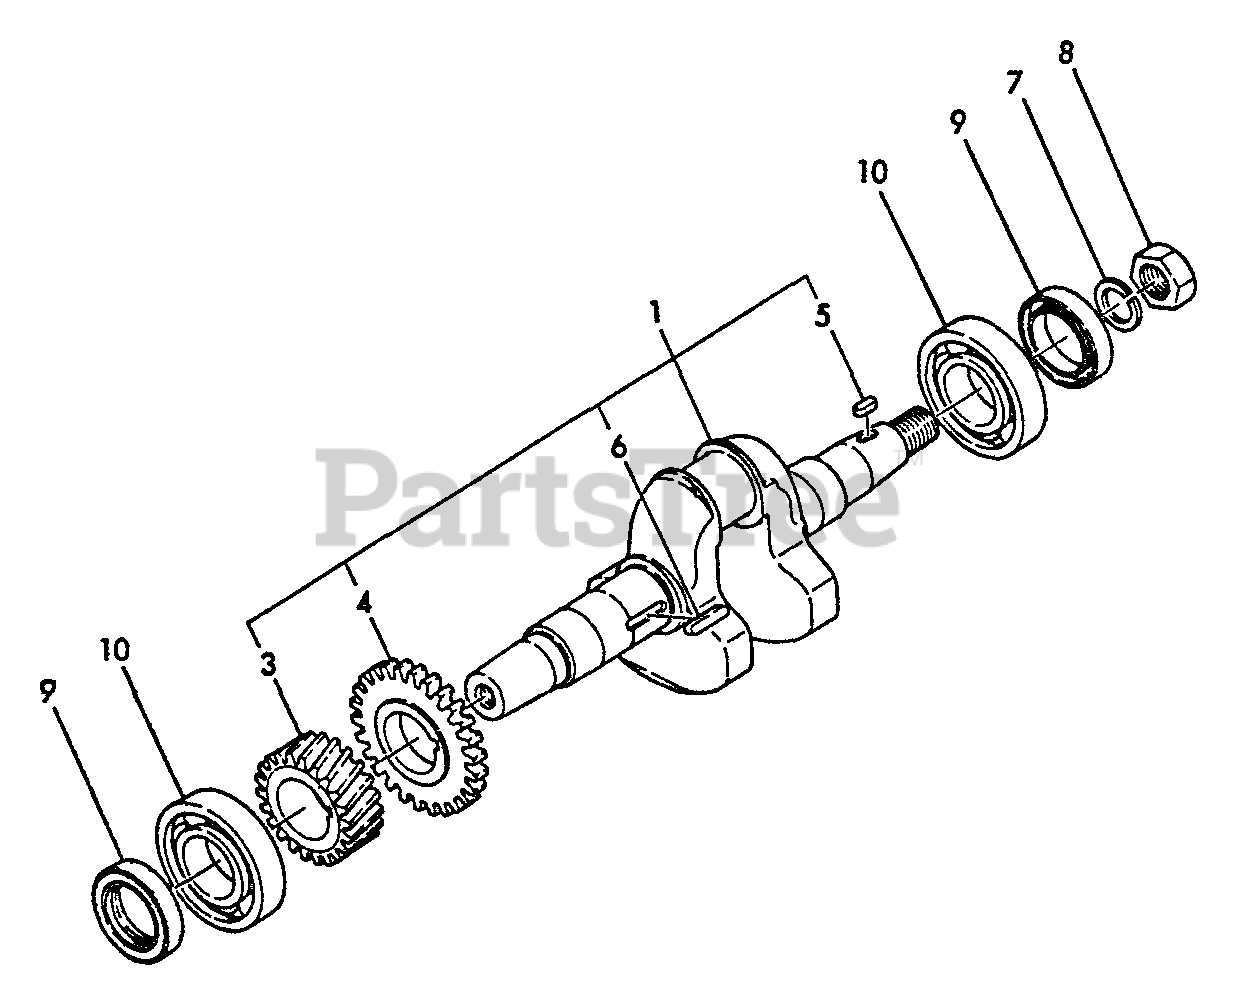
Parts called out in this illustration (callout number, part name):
1	CRANKSHAFT ASSY
3	GEAR, CRANKSHAFT
4	GEAR, BALANCER
5	KEY - 4×10
6	KEY 4×24
7	LOCKWASHER - 10
8	NUT - 16
9	SEAL, OIL
10	BEARING, BALL 6206C4
